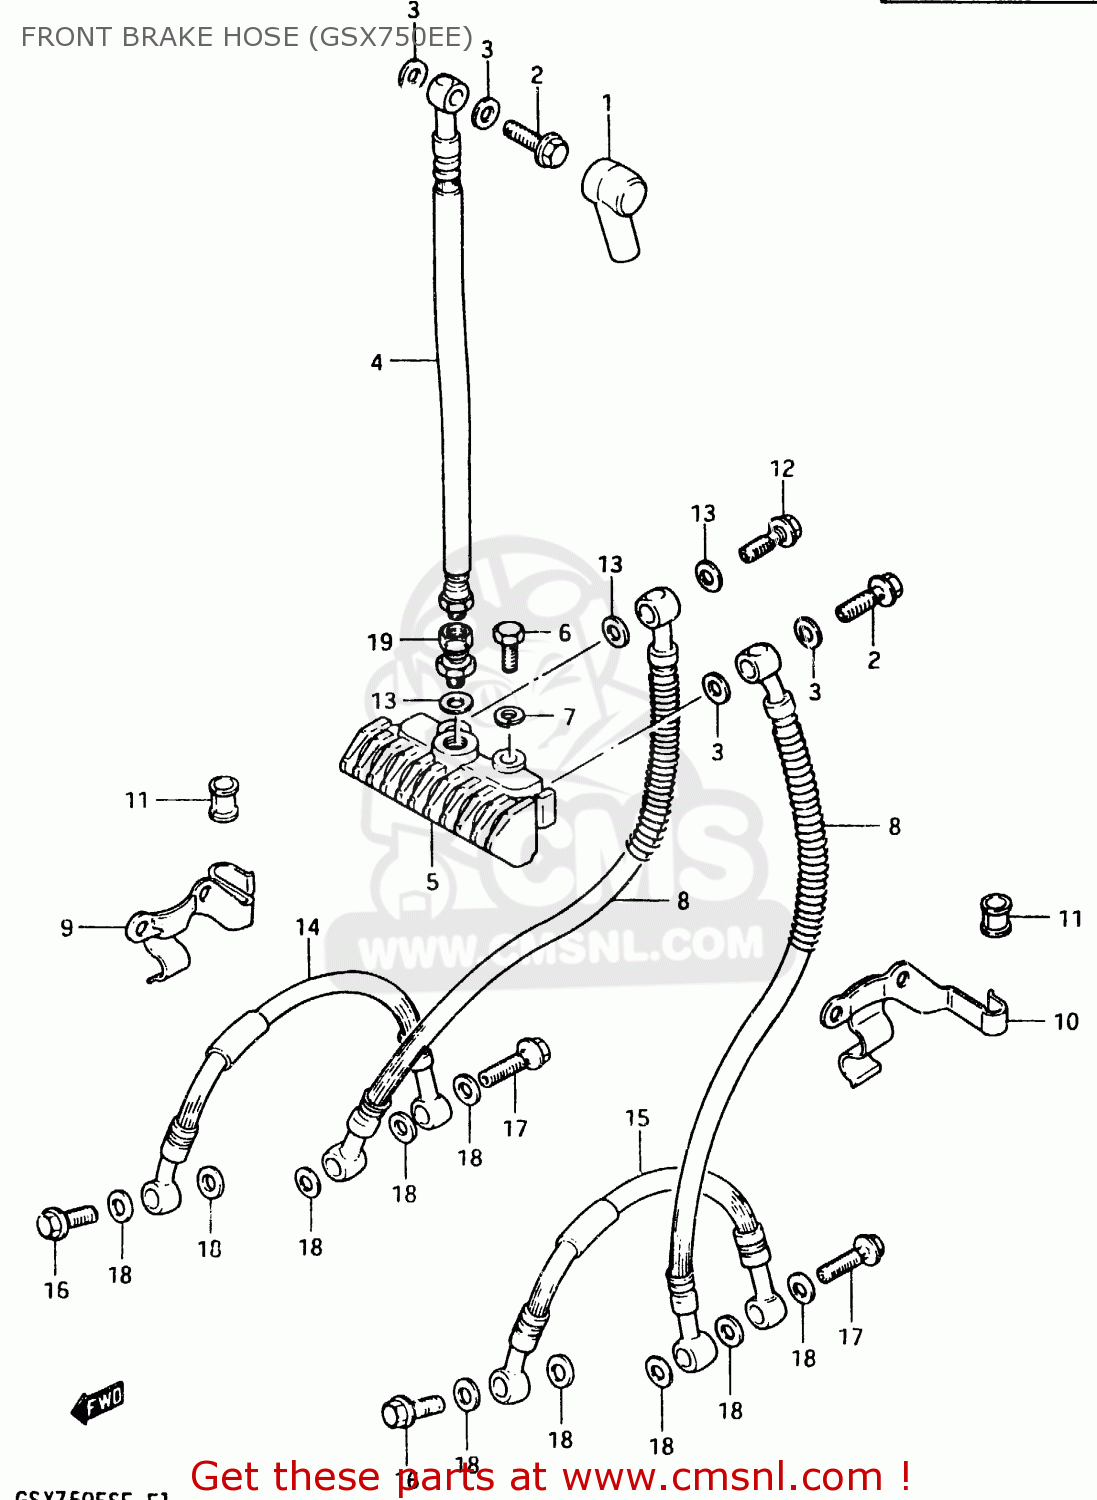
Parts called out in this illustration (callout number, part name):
1	BOOT
2	BOLT UNION
3	WASHER
4	HOSE,FRONT BRAKE NO.1
5	JOINT,BRAKE HOSE
6	BOLT
7	LOCK WASHER
8	HOSE,FRONT BRAKE
9	CLAMP,BRAKE HOSE,RIGHT
10	CLAMP,BRAKE HOSE,LEFT
11	BUSH,BRAKE HOSE GUIDE,NO.2
12	BOLT UNION
13	WASHER
14	HOSE,ANTI-NOSE DIVE
15	HOSE,ANTI-NOSE DIVE
16	BOLT UNION
17	BOLT,UNION
18	WASHER
19	ADAPTER,BRAKE HOSE
